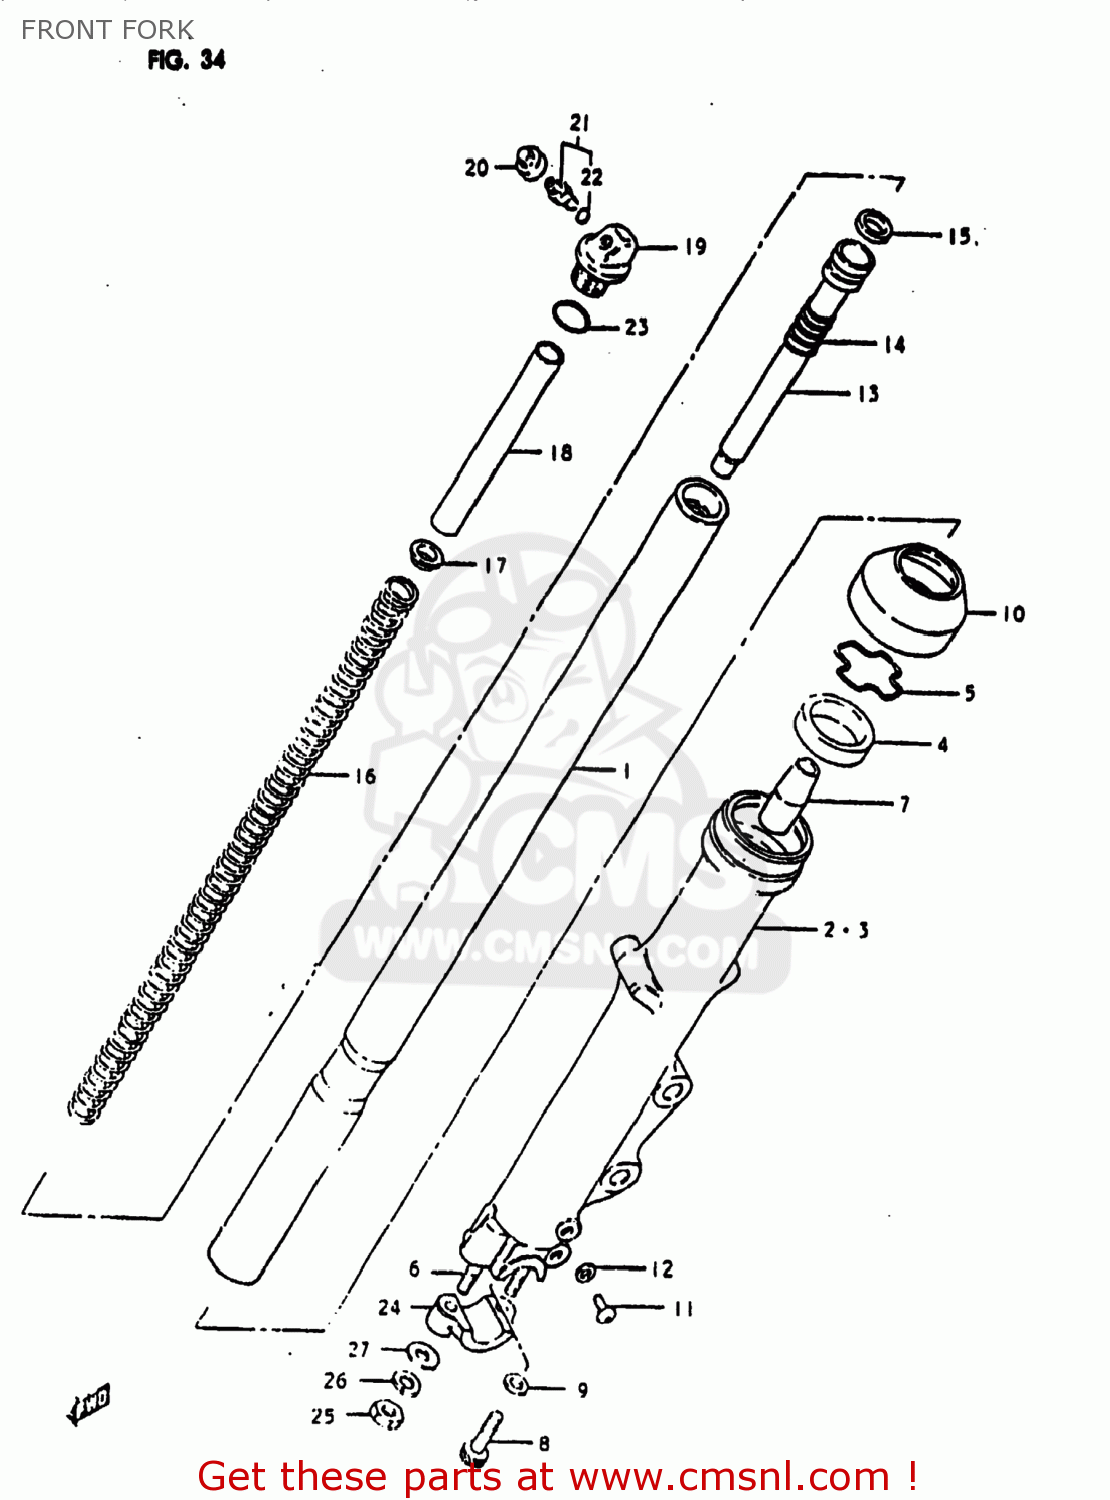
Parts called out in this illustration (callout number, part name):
0	DAMPER ASSEMBLY,LEFT
1	TUBE,FORK,INNER
2	TUBE,FORK,OUTER,RIGHT
3	TUBE,OUTER,LEFT
4	OIL SEAL,FRONT FORK
5	RING,STOPPER
6	STUD BOLT
7	PIECE,OIL LOCK
8	BOLT,FORK CYLINDER(10X25)
9	GASKET (NAS)
10	SEAL,DUST
11	SCREW
12	GASKET,DRAIN,PLUG (NAS)
13	CYLINDER,FRONT FORK
14	SPRING,REBOUND
15	RING,PISTON
16	SPRING,FRONT FORK
17	GUIDE,FRONT FORK SPRING C
18	SPACER,FRONT FORK SPRING
19	CAP
20	CAP,VALVE
21	VALVE
22	O RING
23	O RING
24	HOLDER,AXLE
25	NUT (8MM)
26	LOCK WASHER
27	WASHER
